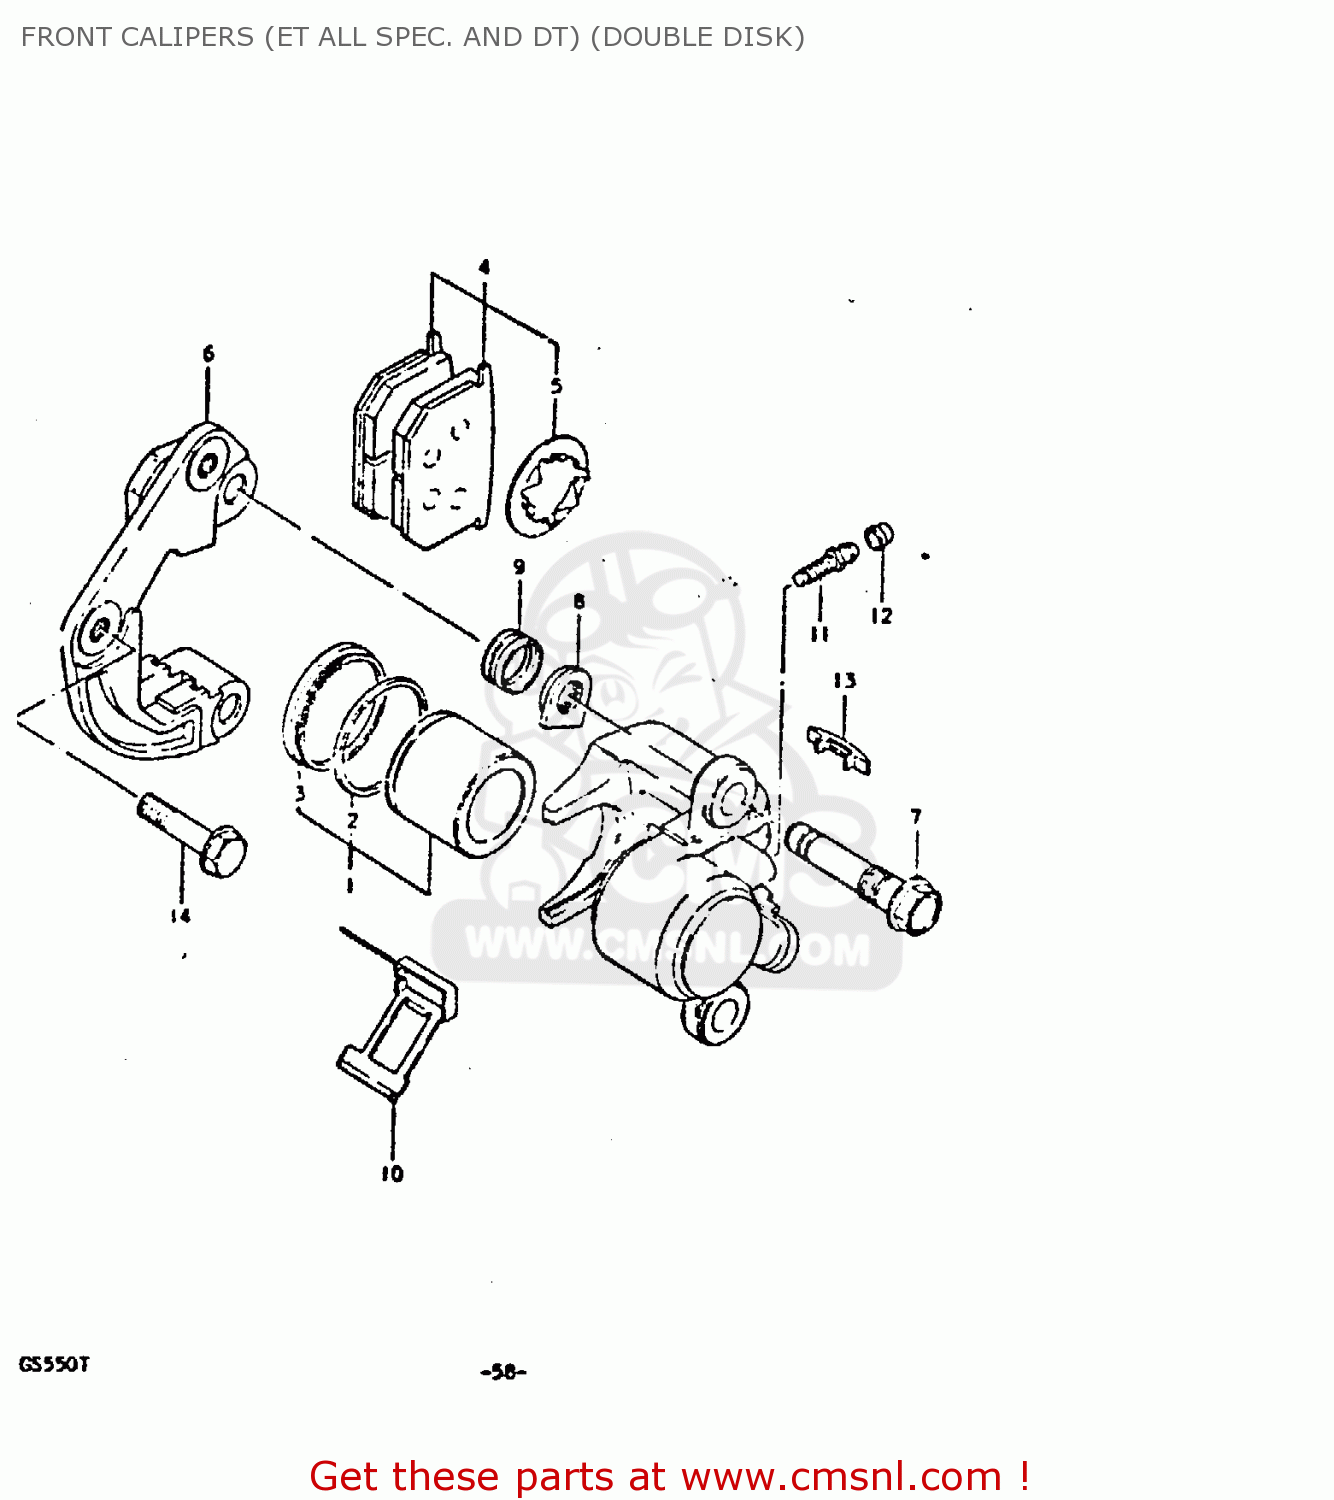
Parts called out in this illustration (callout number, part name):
1	PISTON SET
2	SEAL,PISTON
3	BOOT,PISTON
4	PAD & SHIM SET (MCA)
5	SHIM,PAD
6	BRACKET
7	AXLE,CALIPER
8	NUT,CALIPER AXLE
9	BOOT
10	SPRING
11	BREATHER
12	CAP,BLEEDER PL
13	COVER,INDICATOR
14	BOLT(10X37)
